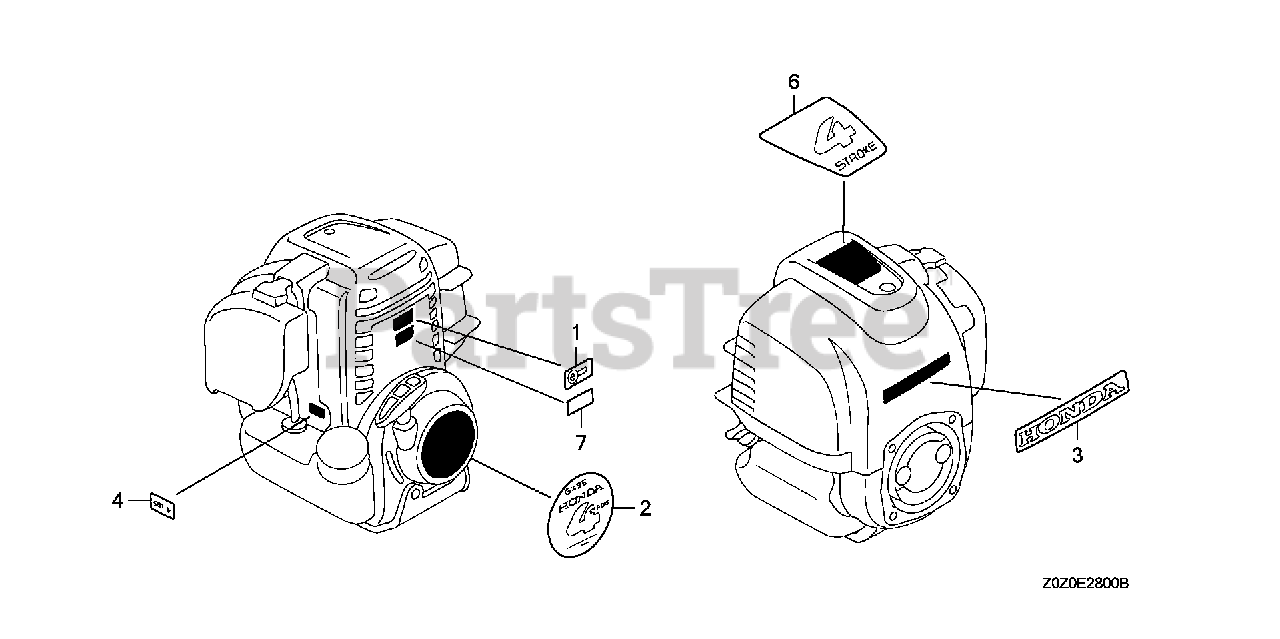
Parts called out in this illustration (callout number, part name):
2	MARK, EMBLEM
3	MARK, HONDA
4	MARK, TYPE (SA2)
6	MARK (4-STROKE)
